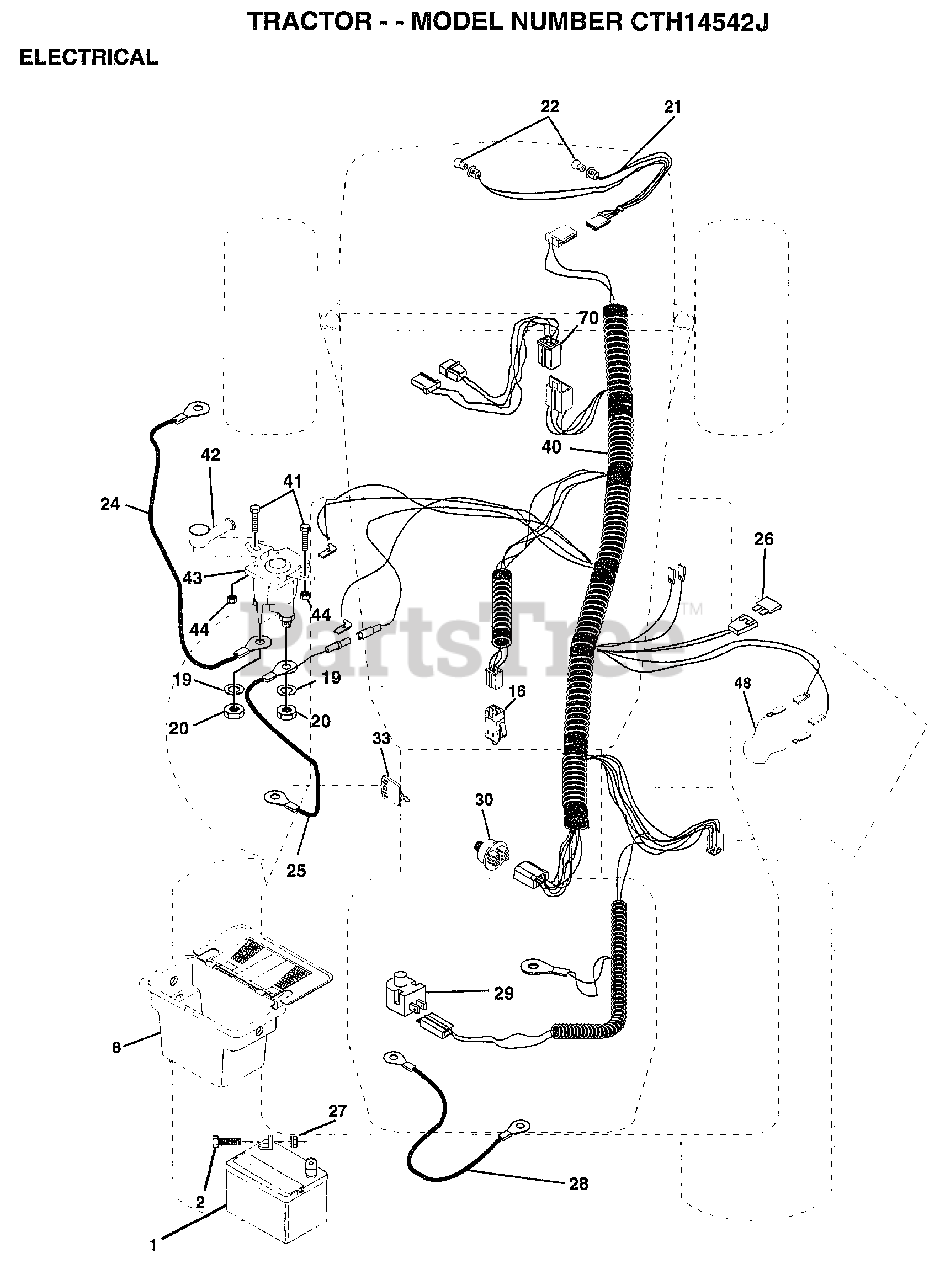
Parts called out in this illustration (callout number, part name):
2	BOLT LT
8	"CASE,BATTERY.MECH"
16	SWITCH INTERLOCK
20	NUT
21	HARNESS.ASM.LIGHT W/4152J
22	HEADLAMP BULB
24	CABLE.BTRY.6GA.RD
25	CABLE.BTRY.6GA.38
26	FUSE.15 AMP
27	NUT
28	CABLE T
29	SWITCH SEAT
30	SWITCH.IGN.
33	KEY MLD GEN DELTA
41	BOLT HXHD FIN
44	NUT HXKEP 1/4X20
48	ADAPTER AMMETER
70	HARNESS.ENGINE.B&S
